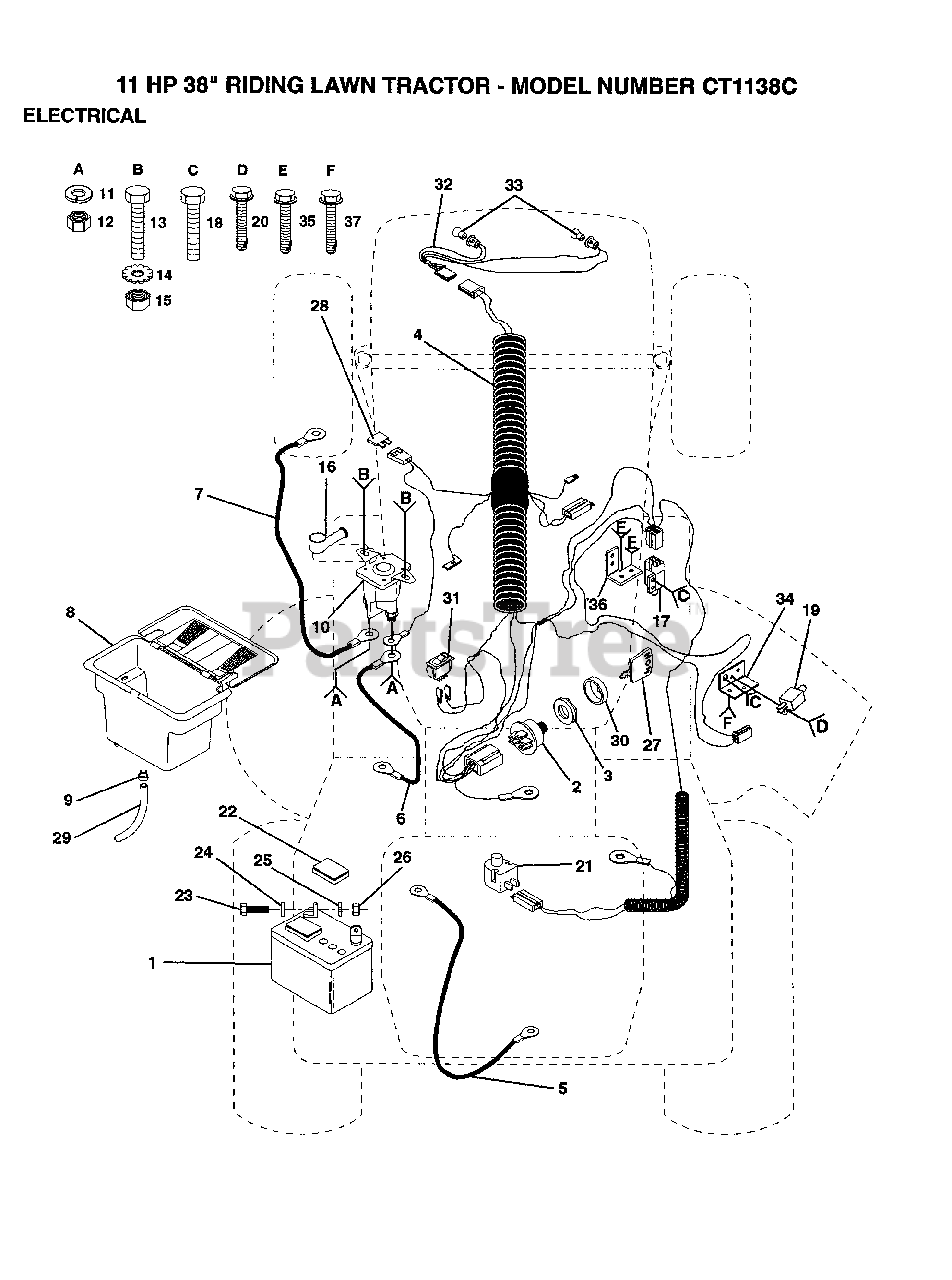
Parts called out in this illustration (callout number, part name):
3	NUT IGNITION
4	IGN HARNESS
5	CABLE T
7	"CABLE T, BATTERY"
9	HOSE CLAMP T
12	NUT
13	BOLT
15	NUT
17	SWITCH INTERLOCKT
18	SCREW
19	SWITCH-INTER. GT
20	SCREW
21	SWITCH SEAT
22	"CAP,BATTERY "
23	BOLT LT
24	WASHER
25	LOCKWASHER
28	FUSE HYT
31	SWITCH LT
32	HARNESS T
34	SWITCH BRACKET
35	SCREW
36	BRACKET LT
37	SCREW
